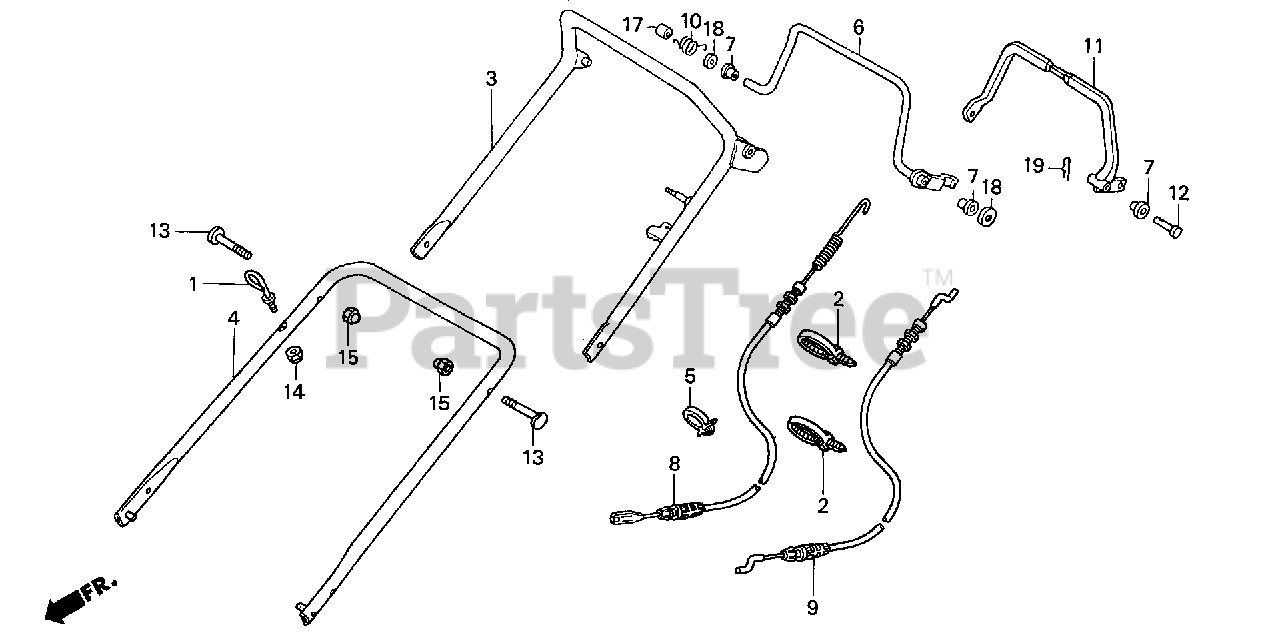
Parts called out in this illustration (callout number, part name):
1	GUIDE, ROPE
2	TIE, CABLE (157.5MM)
3	PIPE, HANDLE (UPPER) *NH105* (MAT BLACK)
4	HANDLE (LOWER) *NH105* (MAT BLACK)
5	CLIP, POWER STEERING SUCTION TUBE
6	LEVER, CLUTCH
7	BUSH, CLUTCH LEVER
8	CABLE, CLUTCH
9	CABLE, BRAKE
10	SPRING, R. STOP RETURN
11	LEVER, BRAKE *NH105* (MAT BLACK)
12	PIN, CLUTCH LEVER
13	BOLT, HANDLE HOLDER
14	NUT, NYLON LOCK (6MM)
15	NUT, CAP (8MM)
17	COLLAR (8X11X13.5)
18	WASHER, PLAIN (8MM)
19	PIN, LOCK (8MM)
